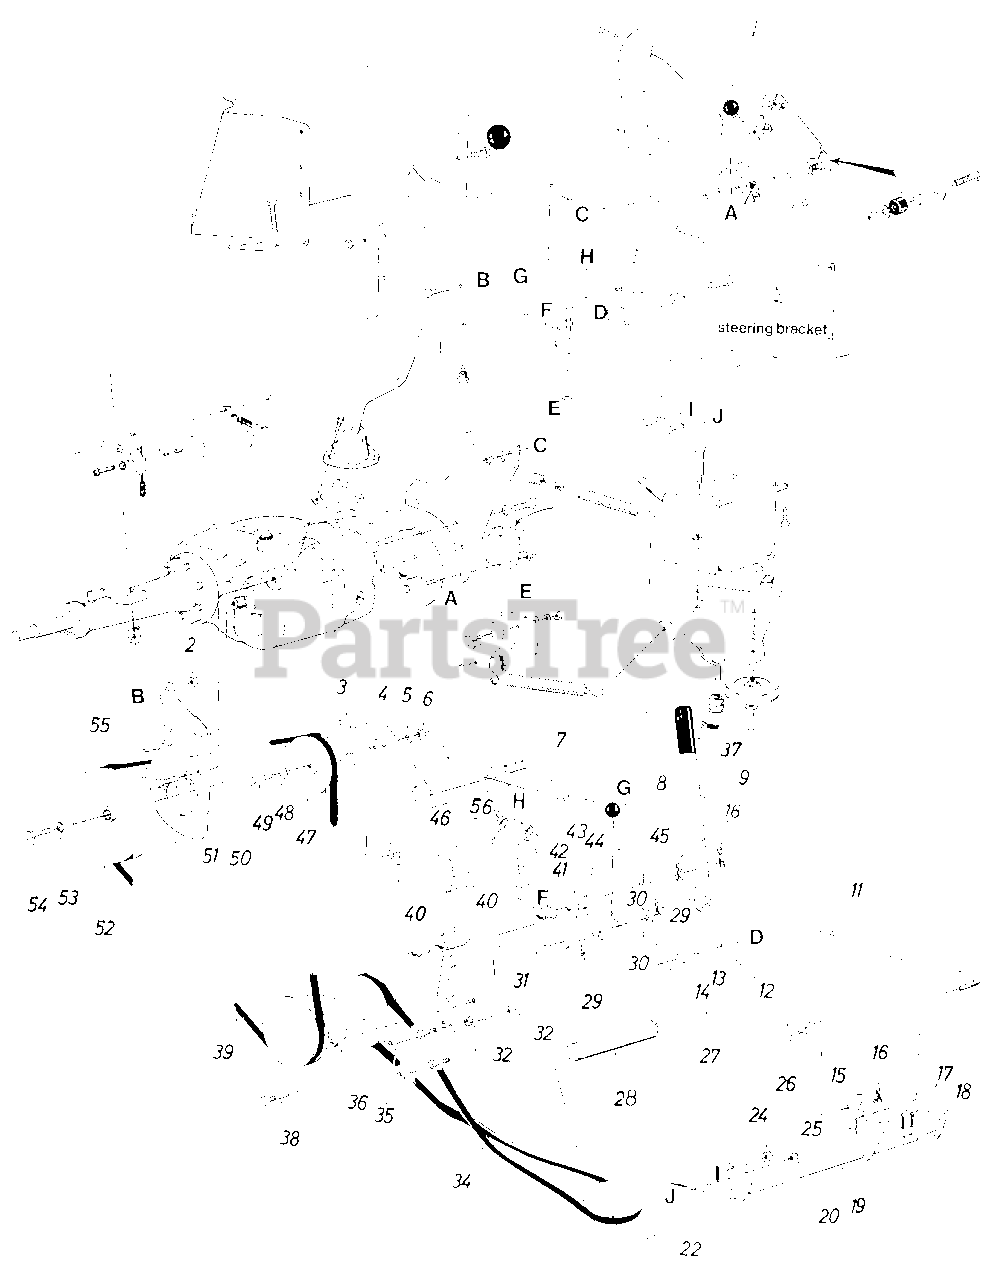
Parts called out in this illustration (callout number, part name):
2	Hex L-Nut 3/8-16 Thd.
5	L-Wash. 3/8" I.D.
6	Hex Nut 3/8-16 Thd.
7	Ext. Spring
8	Knob
9	Hand Brake Lever
11	Brake Rod
12	Parking Brake Cam
13	L-Wash. 5/16" I.D.
14	Hex Nut 5/16-18 Thd.
15	Fl-Wash. 5/16" I.D.
16	Hairpin Cotter 3/8" Rod
17	Cotter Pin 1/8" Dia. x 1.00" Lg.
18	Clutch Rod Brg. Brkt.
19	Clutch Brake Pedal Ass'y.
20	Hex Cent. L-Nut 3/8-16 Thd.
22	Engine Pulley 4.75 & 5.56
24	Hex Cent. L-Nut 3/8-16 Thd.
25	Cotter Pin 3/32" Dia. x .75" Lg.
26	Pivot Bushing
27	Brake Cam Rod
28	Foot Pad
29	Hairpin Cotter 3/8" Rod
30	Fl-Wash. 3/8" I.D. x 1.00" O.D. x .030
31	Jack Shaft Mtg. Brkt. Ass'y.
32	Hex Top L-Nut 3/8-16 Thd.
34	"V"-Belt
35	Stud 3/8-16 X 3.62" Lg. Special
36	Jack Shaft Ass'y.
37	Flat Grip
38	Hex Sem Scr. 5/16-18 X 75" Lg.
39	"V"-Belt
40	Nyliner 5/8" I.D. x .88" Lg.
41	Ext. Spring
42	Hex Thd. Rolling Scr. 1/4-20 X .50" Lg.
43	Clutch-Idler Horn Ass'y.
44	Spring Pin Spiral 1/4" Dia. x 1.00" Lg.
45	Parking Brake Link
46	Idler Mtg. Brkt. Drive
47	4" "V"-Idler Pulley
48	Fl-Wash. 3/8" I.D.
49	Hex Bolt 3/8-16 X 1.75" Lg.
50	L-Wash. 3/8" I.D.
51	Hex Bolt 3/8-16 X .75" Lg.
52	"V"-Pulley 7.0" O.D.
53	L-Wash. 3/8" I.D.
54	Hex Scr. 3/8-24 X 75" Lg.
55	Belt Guard Ass'y.
56	Plastic Hose Clamp
